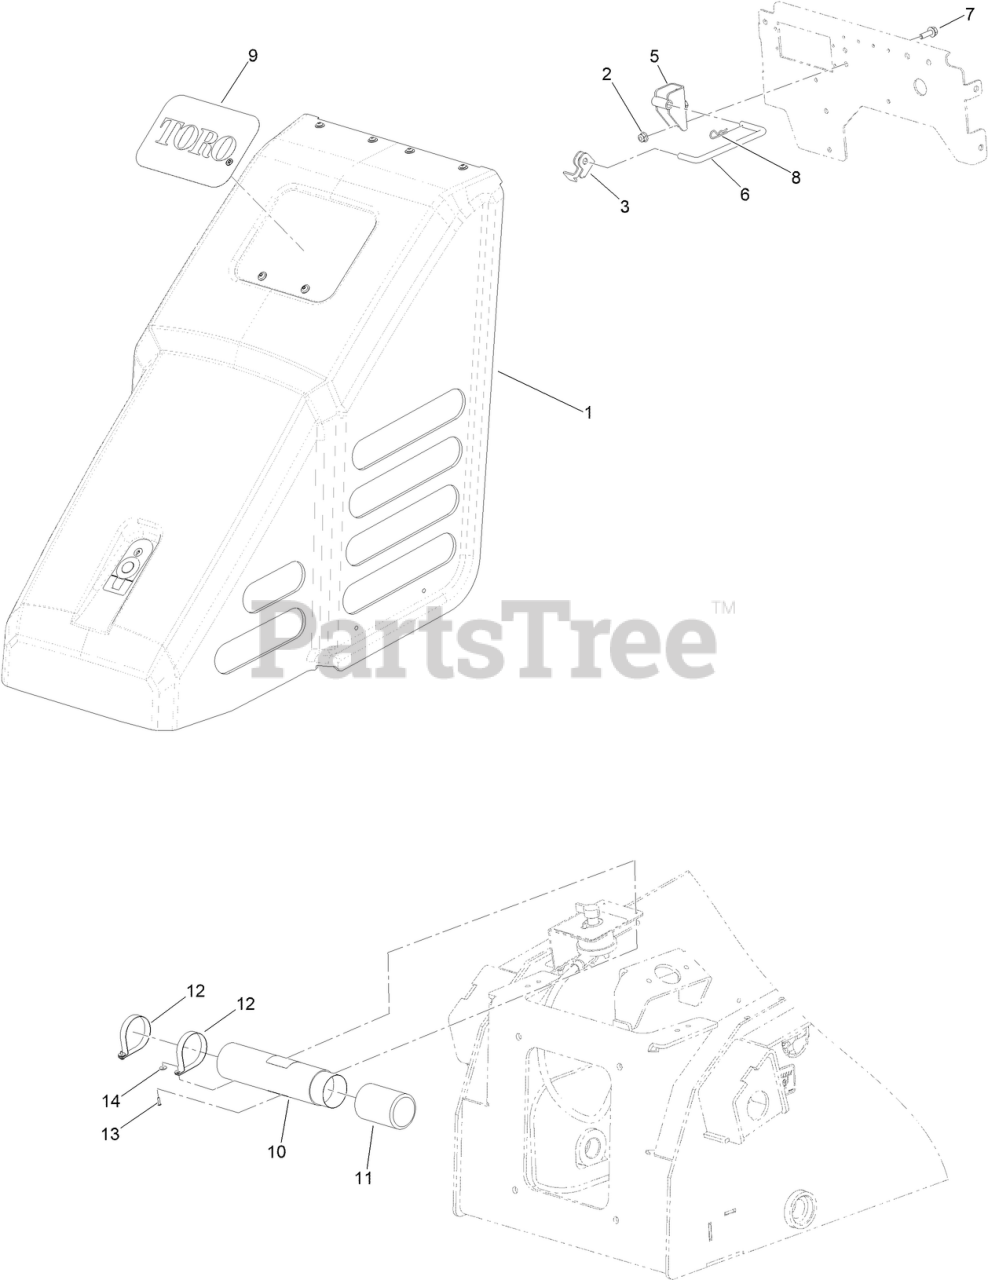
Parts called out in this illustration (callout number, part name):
1	HOOD ASM
2	NUT-HF, NI
3	BRACKET-LATCH, LOCKING
5	BRACKET ASM ROD
6	ROD-SUPPORT,HOOD
7	SCREW-HHF
8	PIN-COTTER
9	DECAL
10	TUBE-MANUAL
11	CAP-HOUSING
12	CLAMP-R
13	RIVET-POP
14	WASHER-BACK
